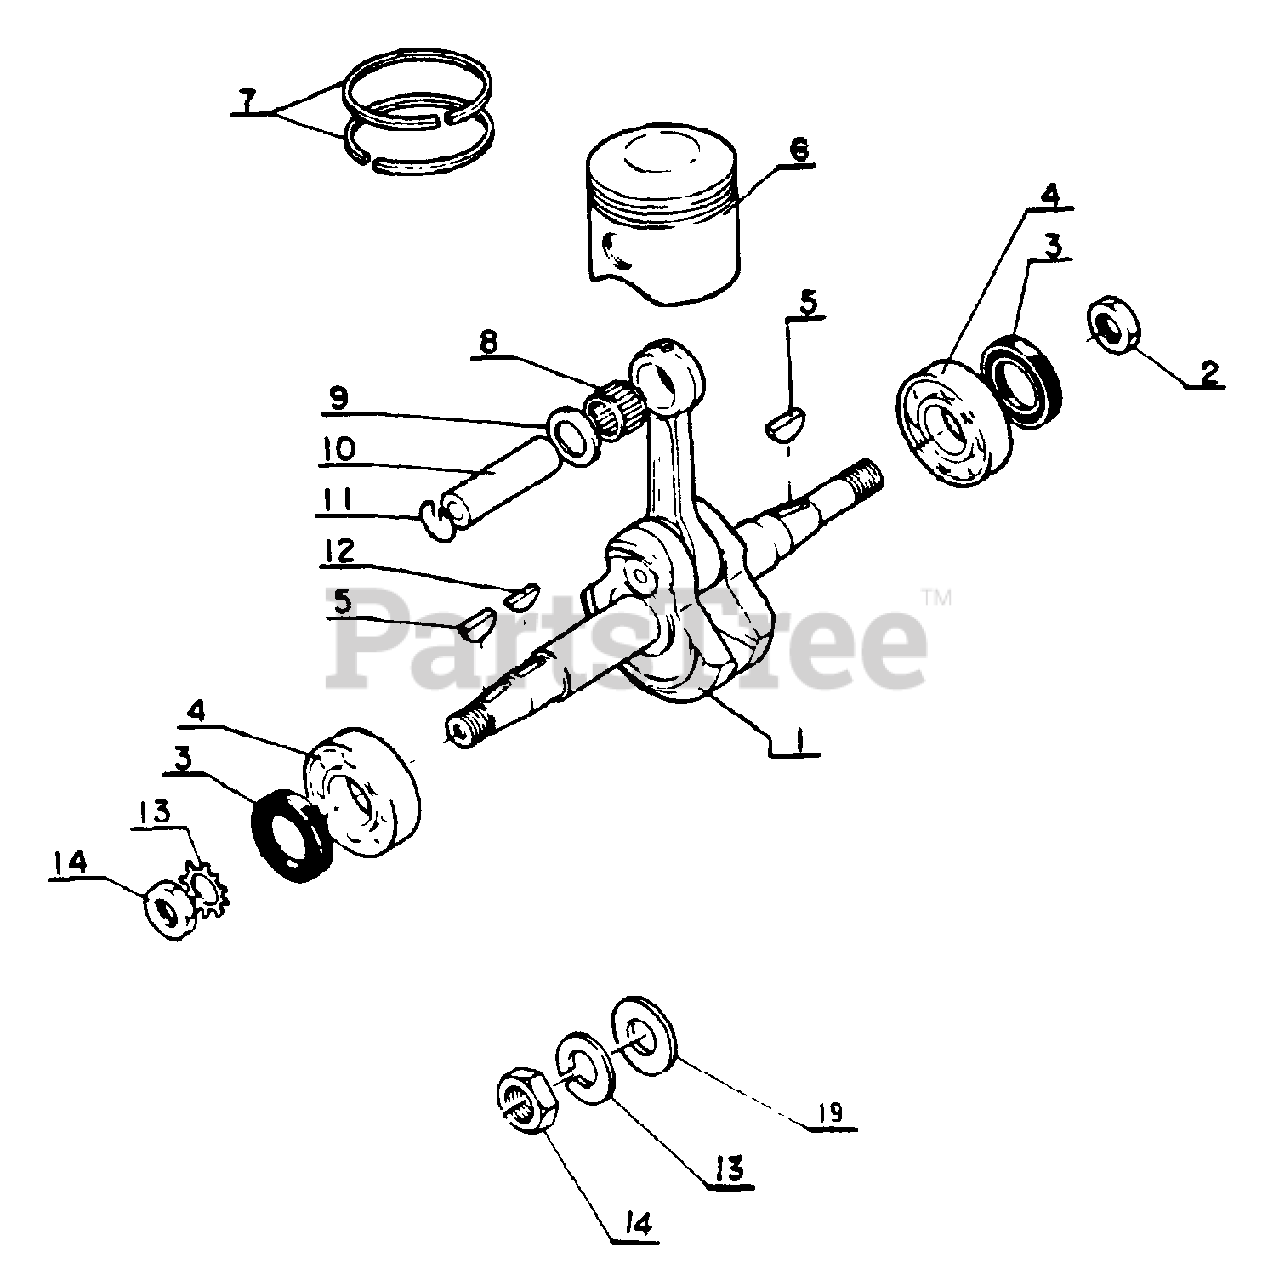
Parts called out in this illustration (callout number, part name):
1	CRANKSHAFT ASSY
2	LOCKNUT
3	SEAL, OIL
4	BEARING, BALL - 6202
5	KEY - 3X14
6	PISTON
7	RING, PISTON
8	BEARING, NEEDLE
9	SPACER, PISTON
10	PIN, PISTON
11	RING, RETAINING - 8
12	KEY
13	LOCKWASHER - 8
19	WASHER - 8
